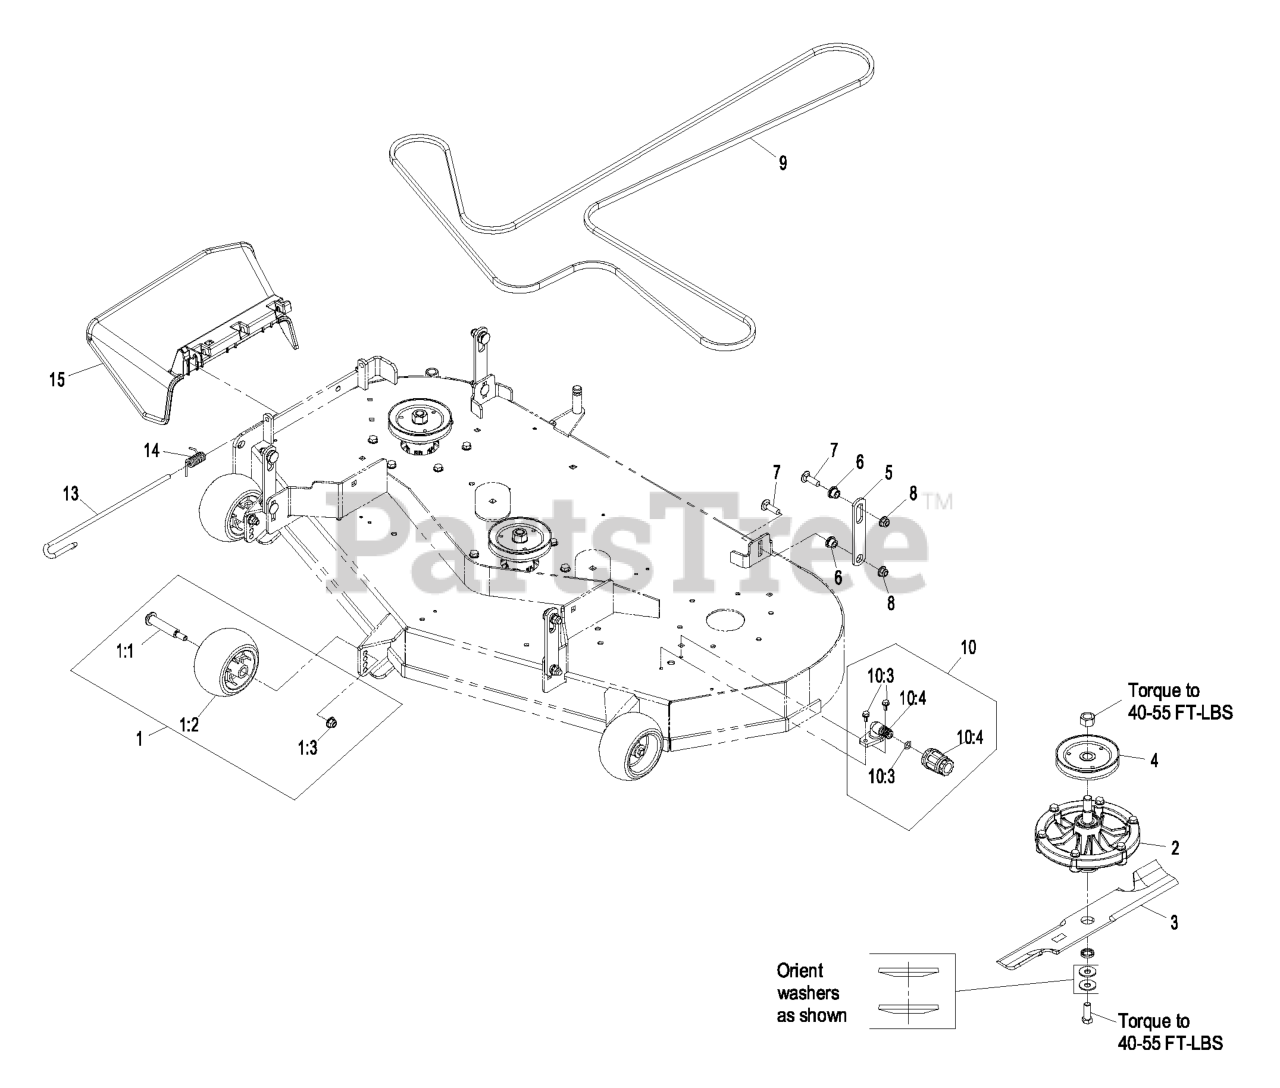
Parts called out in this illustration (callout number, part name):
1	ANTI-SCALP ROLLER KIT
1:1	BOLT-SHOULDER
1:2	ROLLER-SCALP, ANTI
1:3	NUT-HF, NI
5	HANGER-DECK
6	SPACER-STRUT
7	Bolt-Carriage 3/8-16 X 1 1/4
8	NUT-HF, NI
9	BELT
10	WASHOUT PORT KIT
10:3	SCREW-HWH
10:4	CONNECTOR-HOSE
14	SPRING-TORSION
15	CHUTE DEFLECTOR XRK M056
